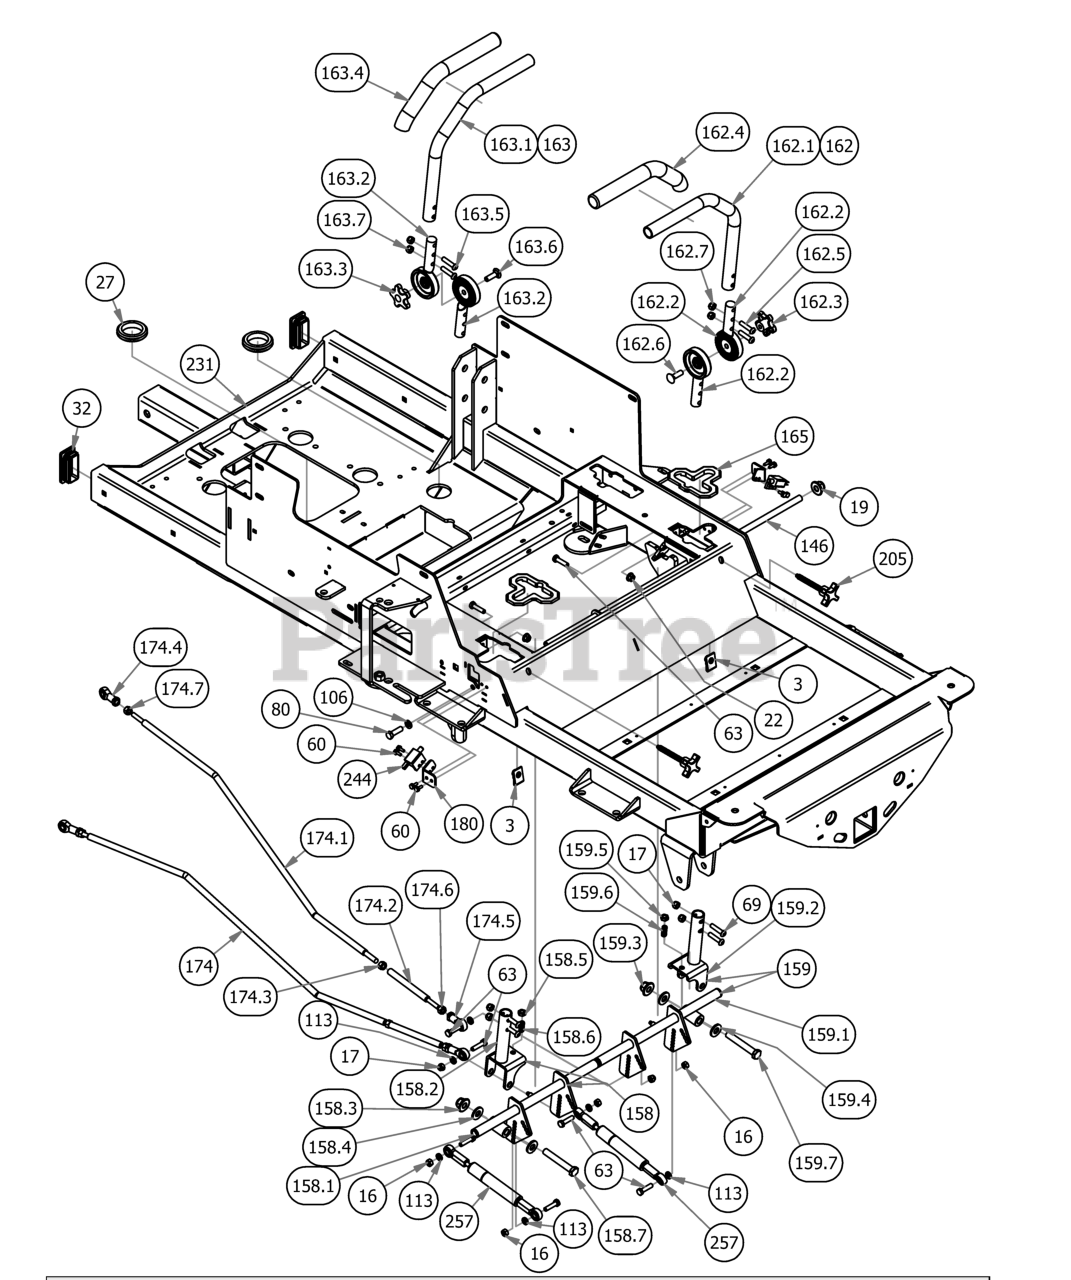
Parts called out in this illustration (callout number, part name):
3	Extruded Nut 3/8"-16 3/4" Hole Center With Patch
19	1/2-13 NYLON INSERT FLANGE LOCKNUT ZINC
22	5/16" Flange Nut
27	2019 2" x .25 Rubber Grommet
32	1 1/2 x 3 Frame Plug
60	12-24x 1/2 HWH Bolt
63	5/16 x 1 1/4 Hex Bolt
69	5/16-18 UNC X 1-3/8" BHCS, TORX DRIVE, GR 5
80	3/8" x 1 1/4" Hex Bolt
106	3/8" Lock Washer
113	5/16" Lock Washer
146	2019 Steering Actuator Rod
158	2019 R Series RH Arm Rod Assembly
158.1	2019 Drive Arm Actuator right
158.2	Drive Arm Pivot
158.3	1/2-13 NYLON INSERT FLANGE LOCKNUT ZINC
158.4	.505 Nylon Spacer
158.5	3/8-16 Half Jam Nut
158.6	3/8-16 x 1 Set Socket Set Screw Cup Point
158.7	1/2-13 x 3.25 GR 5 Hex Bolt Zinc
159	2019 R Series LH Arm Rod Assembly
159.1	2019 Drive Arm Actuator left
159.2	Drive Arm Pivot
159.3	1/2-13 NYLON INSERT FLANGE LOCKNUT ZINC
159.4	.505 Nylon Spacer
159.5	3/8-16 Half Jam Nut
159.6	3/8-16 x 1 Set Socket Set Screw Cup Point
159.7	1/2-13 x 3.25 GR 5 Hex Bolt Zinc
162	2019 Left Hand ADJ. Steering Arm Kit
162.1	2019 Steering Arm Grip
162.2	2019 Steering Arm Adjuster Casting
162.3	Black Knob for Adjustable Steering Arm
162.4	Black Steering Arm Grip
162.5	5/16-18 UNC X 1-3/8" BHCS, TORX DRIVE, GR 5
162.6	3/8" x 1 1/4" Carriage Bolt
162.7	5/16-18 Nylock Insert Locknut
163	2019 Right Hand ADJ. Steering Arm Kit
163.1	2019 Steering Arm Grip
163.2	2019 Steering Arm Adjuster Casting
163.3	Black Knob for Adjustable Steering Arm
163.4	Black Steering Arm Grip
163.5	5/16-18 UNC X 1-3/8" BHCS, TORX DRIVE, GR 5
163.6	3/8" x 1 1/4" Carriage Bolt
163.7	5/16-18 Nylock Insert Locknut
165	Snap-In Bushing-2019
174	2019 Outlaw Gen2 Horizontal Push Rod Assembly
174.1	2019 Outlaw Gen2 Horizontal Push Rod
174.2	2019 Outlaw Gen2 Horizontal Push Rod Adjuster
174.3	3/8" Fine Threaded Jam Nut
174.4	Spherical Rod End - Outlaw
174.5	Spherical Rod End - Outlaw
174.6	5/16" LH Fine Threaded Jam Nut
174.7	5/16" RH Fine Threaded Jam Nut
180	2019 Arm Switch Bracket
205	Speed Limiting Knob 3/8-16X 3"
231	2019 Horizontal Diesel Frame
244	Safety Switch
257	2019 SROID Damper With Spherical Rod Ends
